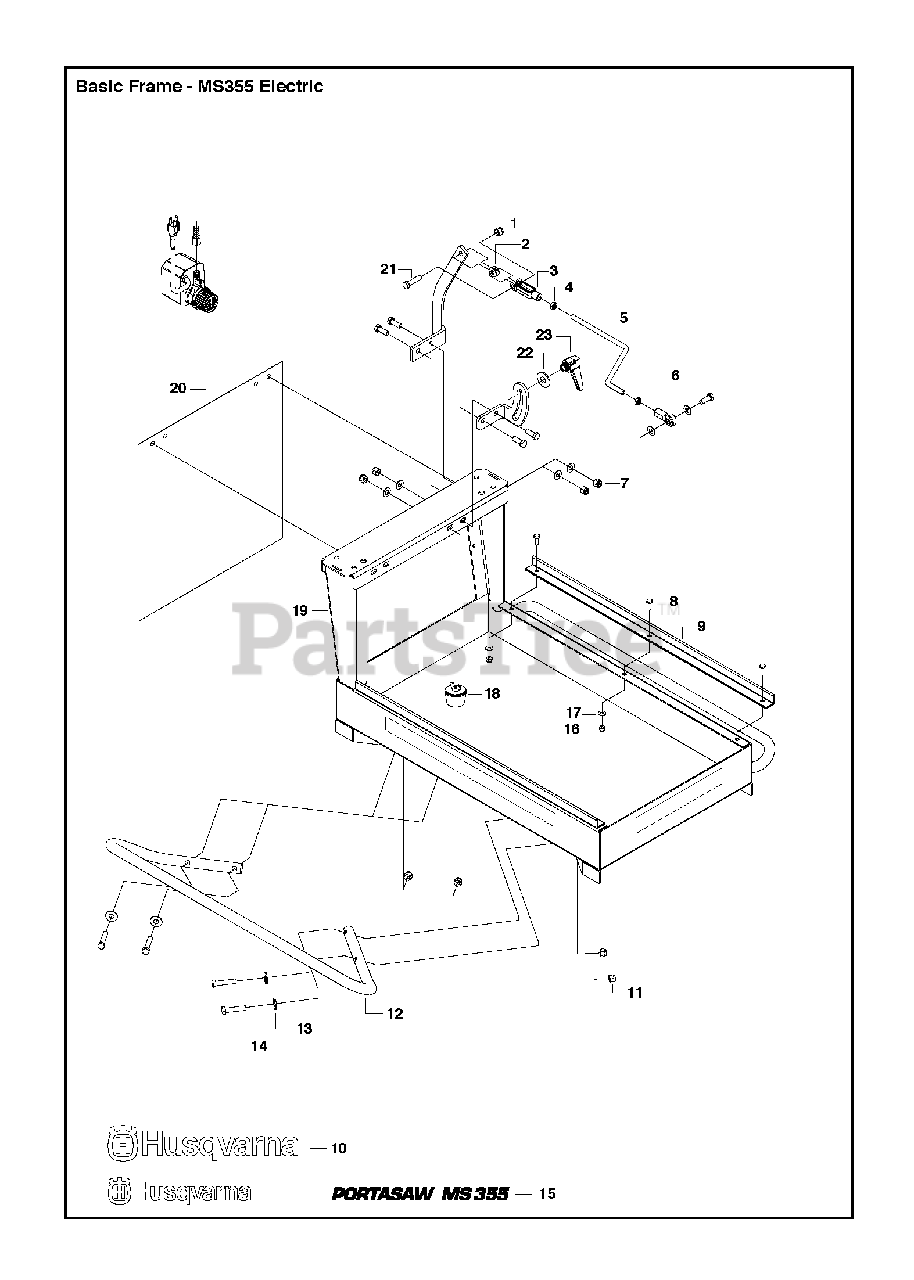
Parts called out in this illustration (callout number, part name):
1	NUT
2	WASHER
7	NUT
13	U-SCHEIBE/* 020743 REF.53
16	NUT
17	WASHER 1/4 SAE
